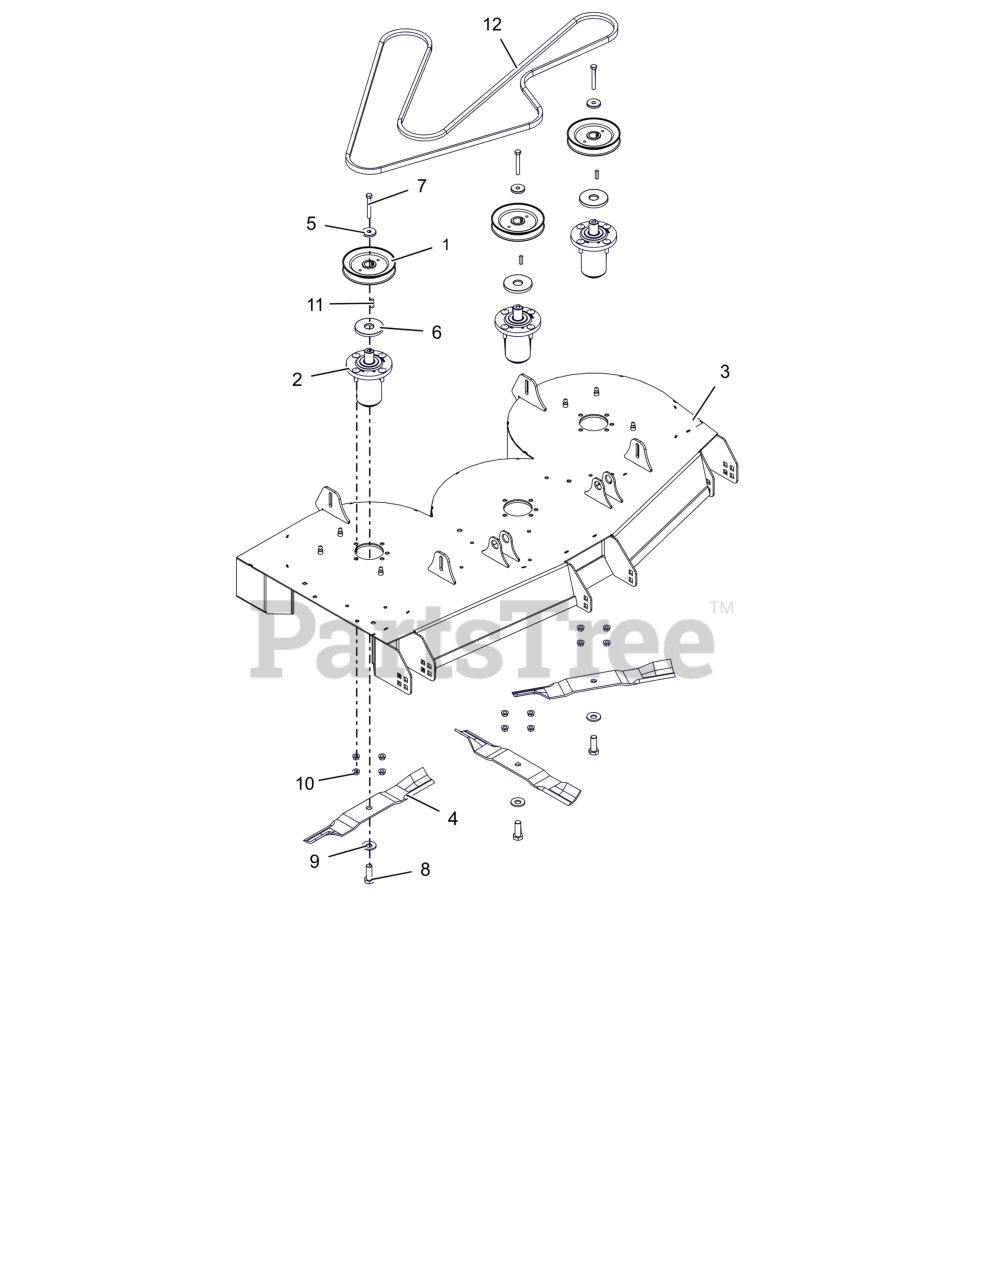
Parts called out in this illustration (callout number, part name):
1	PULLEY- V-1.000 ID X 5.750 OD
2	ASM, ALUM SPINDLE
3	52 DECK WLDMT W/SAFETY DECALS
4	BLADE, 18"
5	RETAINER, SHEAVE
6	SPCR- SHEAVE SPINDLE
7	BLT, HEX .38-16X2.75 G8 ZCC
8	BLT, HEX .62-18X1.75 G8 ZCC
9	WSHR-BLVL .669X1.535X.138
10	NUT-LK-CTR-FLG .375-16 GF ZCC
11	KEY, SQ .25X.25X1.00 RC 40-50
12	V-BELT, B SECTION RAW EDGE
